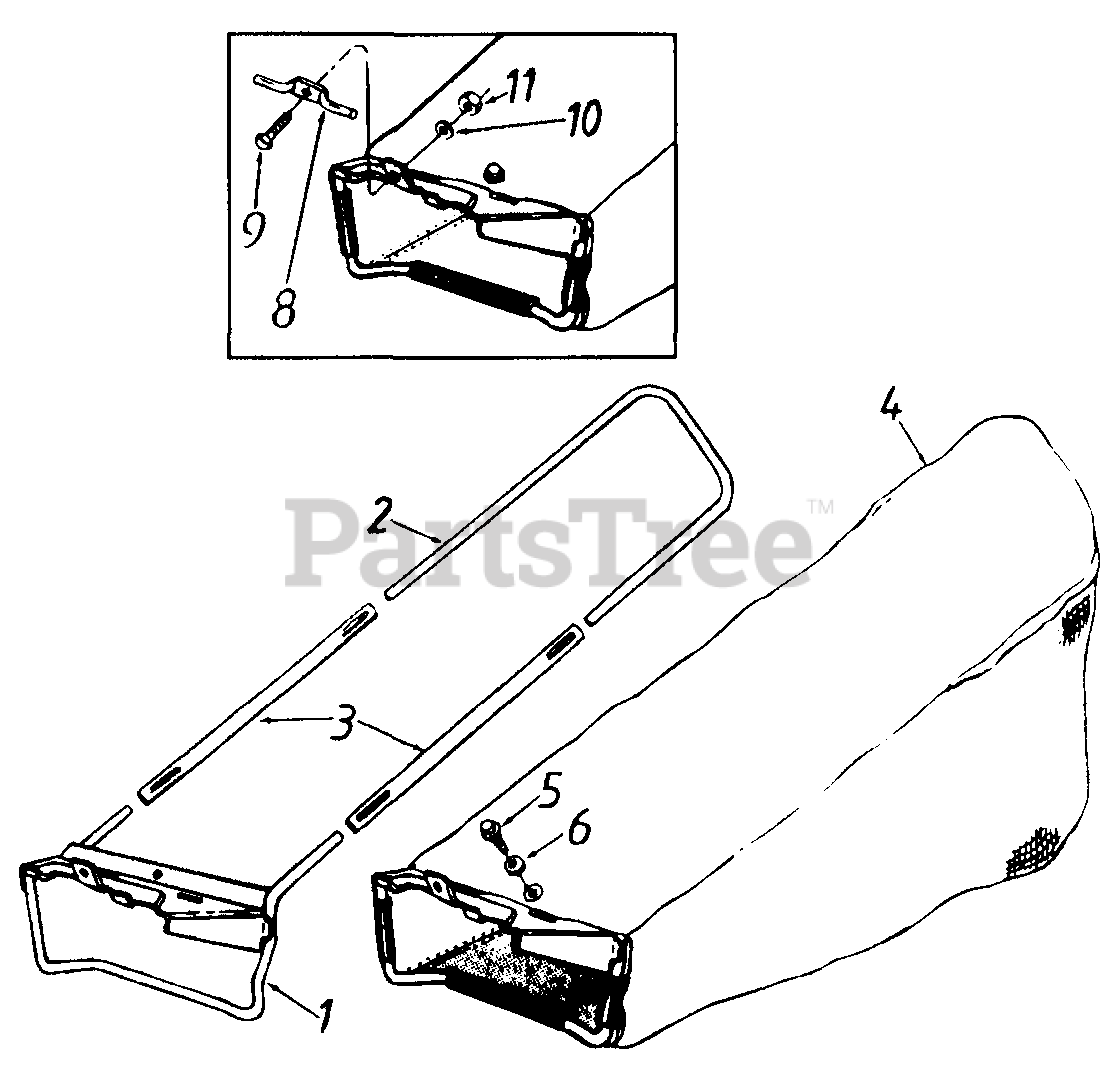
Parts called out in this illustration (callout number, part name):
4	Grass Bag
5	Hex Wash. Hd. TT-Tap Scr. 1/4-20 x 5" Lg.
6	Bell-Wash. 1/4" I.D.
8	Grass Bag Hook
9	Hex Bolt 1/4-20 x .62" Lg.
10	L-Wash. 1/4" I.D.
11	Hex Nut 1/4-20 Thd.
